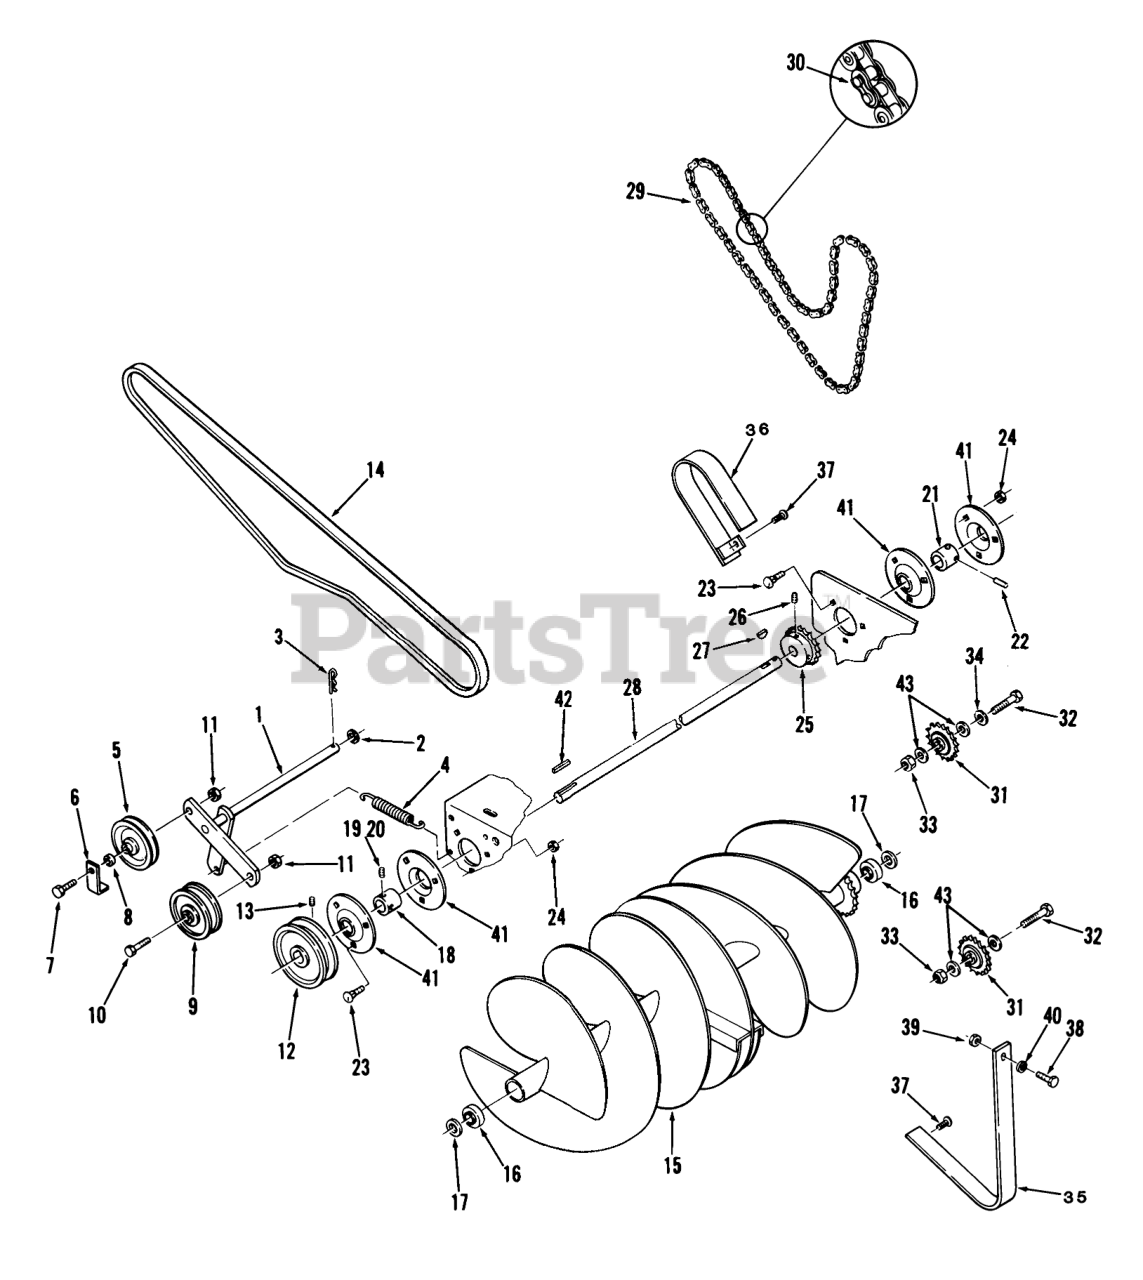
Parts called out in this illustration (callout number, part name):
1	ASSY IDLER ARM R
2	Washer
3	Hairpin
4	SPRING R
5	PULLEY-IDLER
6	Spacer
7	Bolt
8	SPACER
9	Idler Pulley
10	BOLT
11	Nut
12	Pulley
13	Set Screw
14	V-BELT
15	Auger
16	BEARING-BALL
17	Washer
18	Ball Bearing
19	Set Screw
20	SET SCREW
21	Ball Bearing
22	PIN-ROLL, SPIROL
23	Bolt
24	Nut
25	SPROCKET
26	SCREW-SET
27	Key
28	SHAFT
29	CHAIN
30	MASTER LINK CHAIN
31	Idler Sprocket
32	H H C S
33	Eslok Nut
34	SPACER
35	Guard-Inner
36	Guard-Outer
37	SCREW
38	H H C S
39	Nut 1/4-20
40	WASHER
41	FLANGE
42	KEY-STRAIGHT
43	Washer
